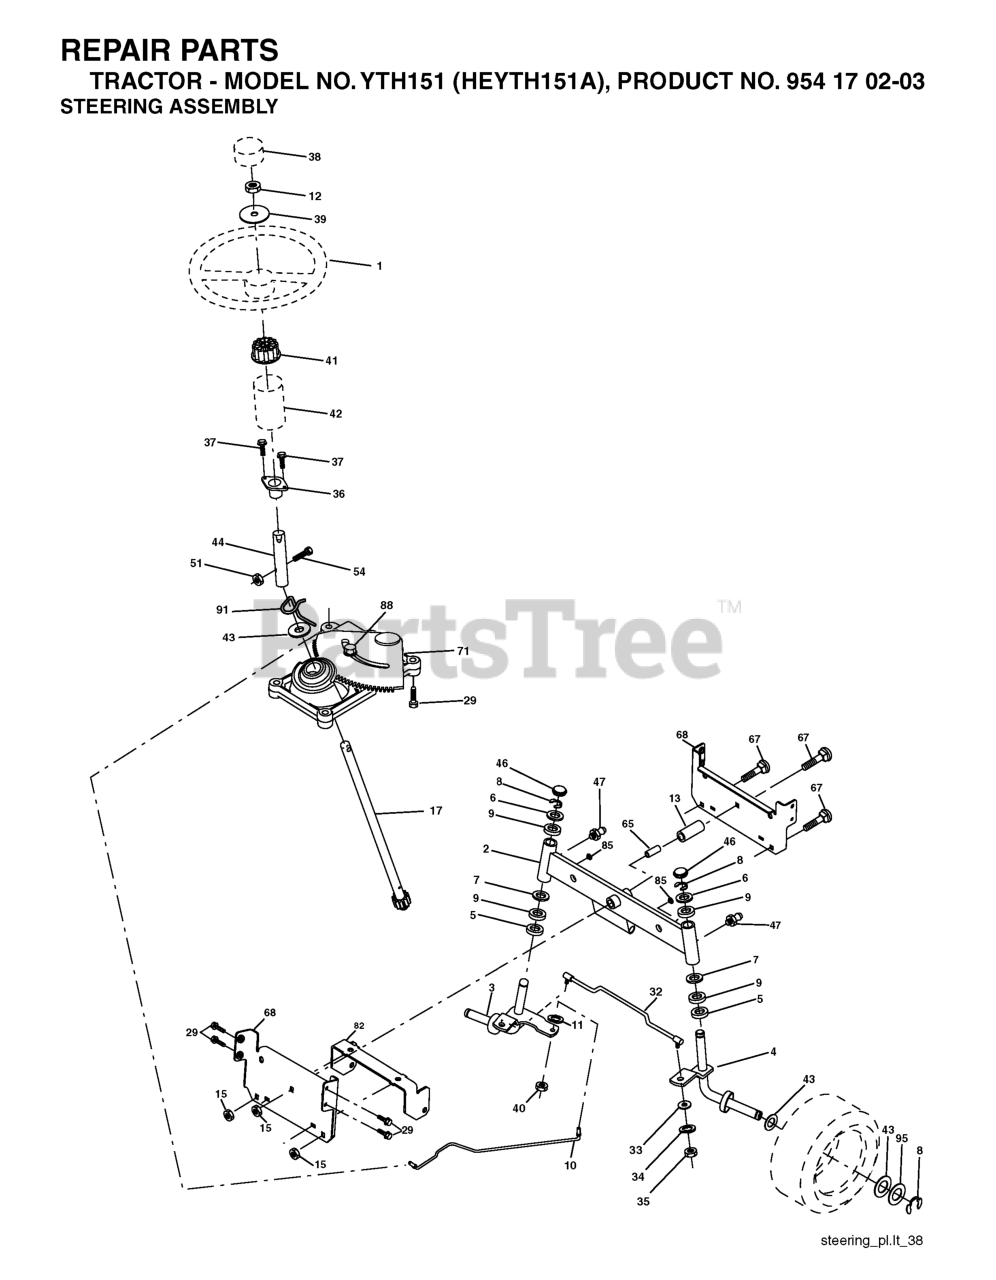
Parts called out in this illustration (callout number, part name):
1	STEERING WHEEL
2	AXLE ASM.
3	SPINDLE.ASM.LH.15"TIRES
4	SPINDLE.ASM.RH.15"TIRES
5	THRUST WASHER
9	BRNG T
10	DRAGLINK.15".TIRES.2001
11	WASHER, LOCK 3/8
12	NUT.HEX.1/2-20
13	TUBE, PIVOT AXLE
15	NUT
17	SHAFT ASM, STEERING
29	SCREW, 3/8-16X3/4
33	WASHER M
34	WASHER.LOCK.HVY.HLCL.SPR.5/16
35	NUT, CROWNLOCK
36	BUSHING, STEERING
37	SCREW.TT.#10-32X.5.3/8.FLANGE
38	CAP.WHEEL.STEERING.GREY
39	Washer 9/16 ID x 1 1/2 OD 11 Ga. Zin
40	NUT CROWNLOCK 3/8-24
41	STEERING WHEEL ADAPTOR
42	BOOT STEERING
44	EXT, STEERING SHAFT
46	CAP.SPINDLE.BLACK
47	FITTING.GREASE.TAPERED
51	NUT.CROWNLOCK.1/4-28
54	Bolt Hex 1/4-28 unf x 1-1/4 Gr. 8
65	SPACER BRACE AXLE
67	BOLT CARRIAGE
68	BRACE.AXLE.15"TIRES
71	STEERING ASM
82	BRACKET
85	FASTENER.XMAS.TREE
88	BOLT, SHOULDER 7/16-20
91	CLIP.STEERING
95	WASHER.HARDENED
